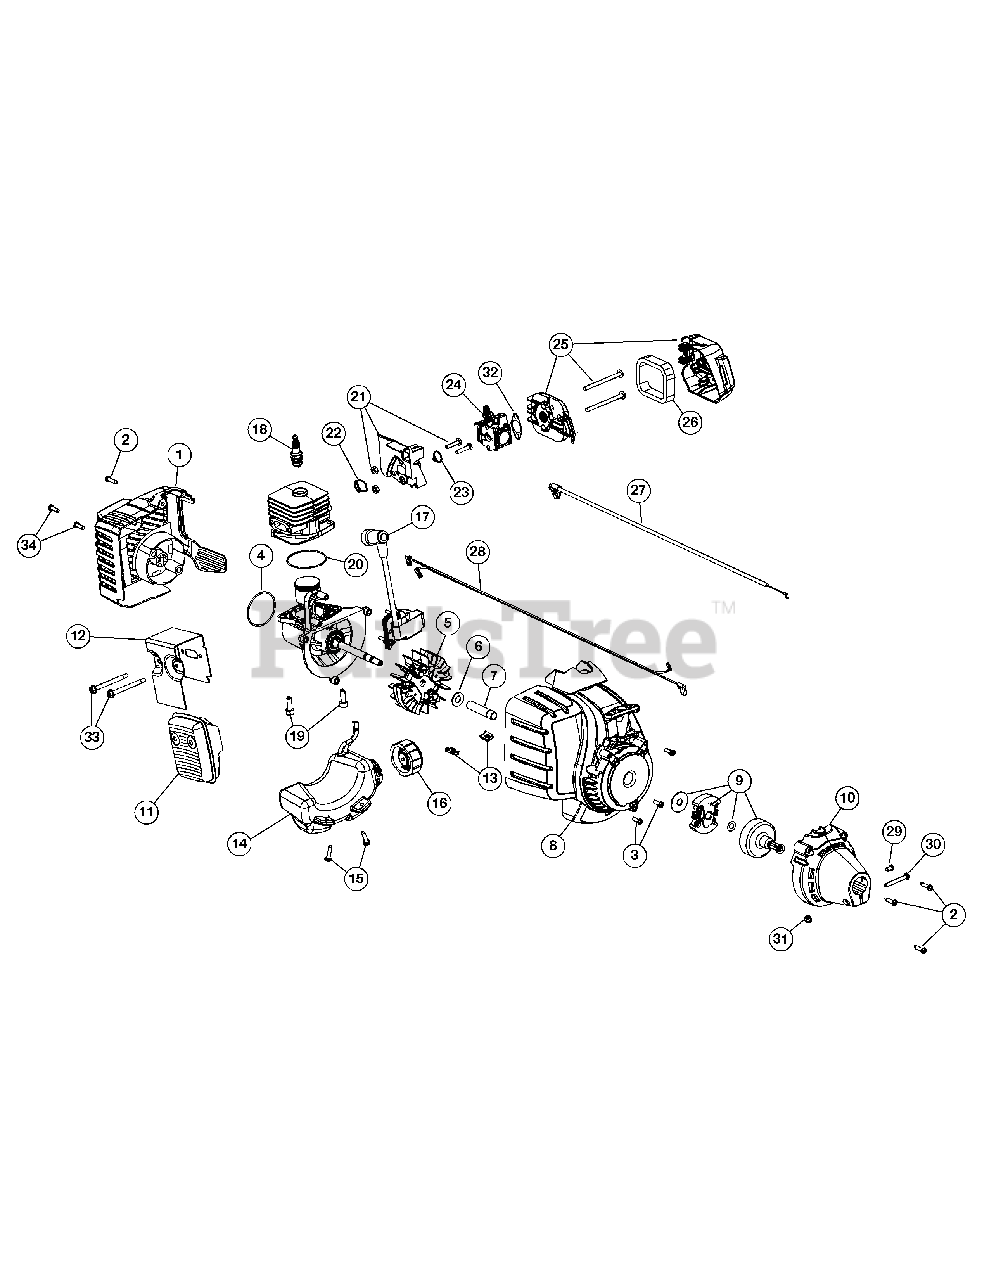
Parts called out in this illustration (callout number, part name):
1	Rear Cover Assembly (Incl. 2 - 4)
2	Cover Screw
3	Housing Screw
4	O-Ring
5	Flywheel Assembly
6	Washer
7	Spacer
8	Starter Housing (Incl. 3 & 13)
9	Clutch Assembly
10	Clutch Cover (Incl. 2)
11	Muffler Assembly (Incl. 12 & 33)
12	Muffler Gasket
13	U-shaped Nut
14	Fuel Tank Assembly (Incl. 15 & 16)
15	Tank Screw
16	Fuel Cap
17	Module Assembly
18	Spark Plug
19	Crankcase Bolt
20	Crankcase O-Ring
21	Insulator Assembly (Incl. 22 & 23)
22	Insulator O-Ring
23	Carburetor O-Ring
24	Carburetor
25	Aircleaner Cover Assembly (Incl. 26)
26	Aircleaner Filter
27	Throttle Cable
28	Lead Wires
29	Anti-rotation Screw
30	Clamp Screw
31	Clamp Nut
32	Air Cleaner Gasket
33	Muffler Screw
34	Rear Housing Screw
